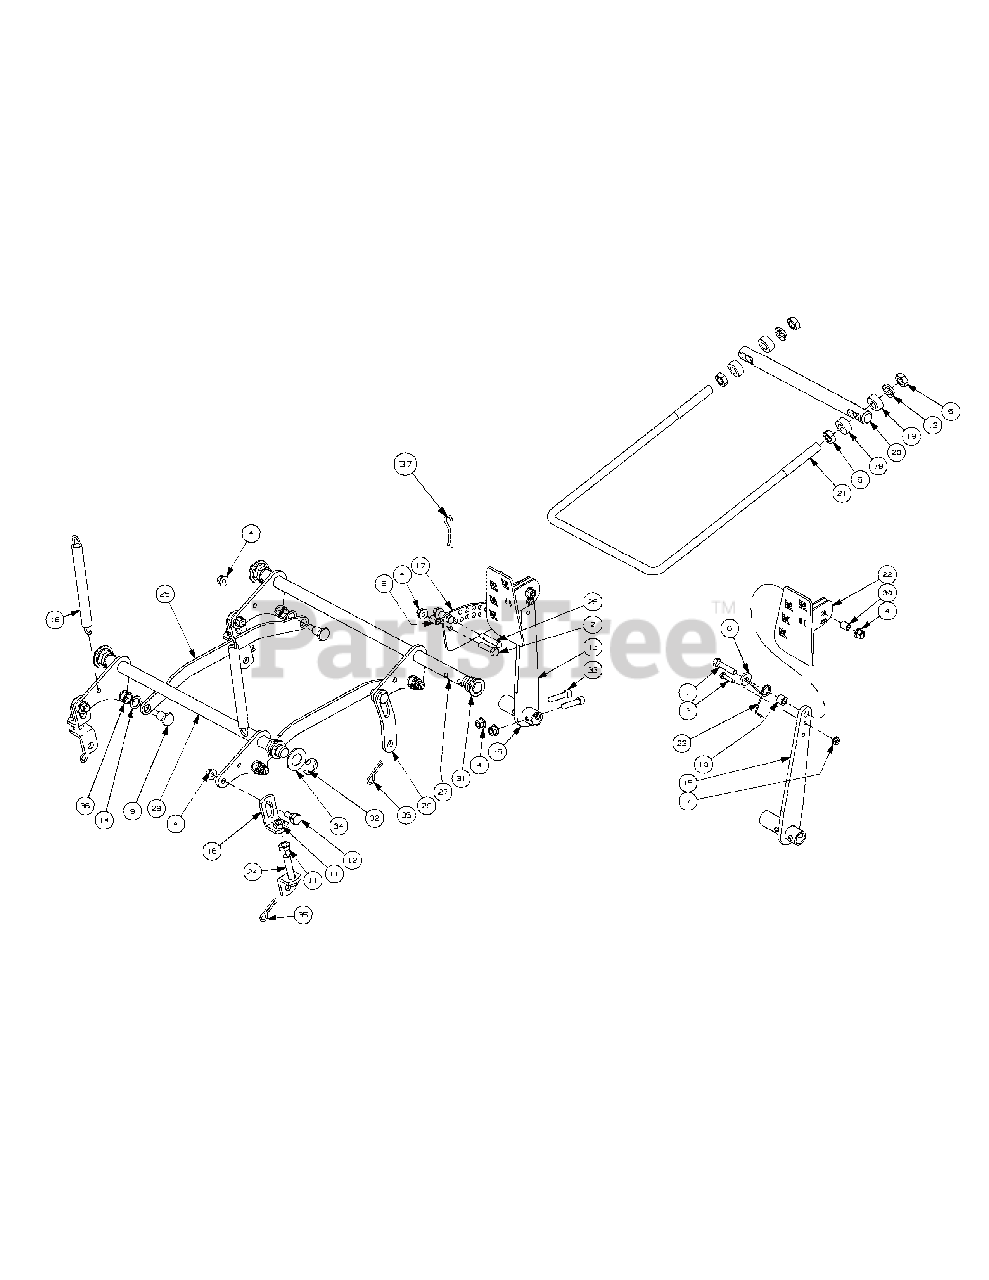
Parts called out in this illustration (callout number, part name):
1	Capscrew, 3/8-16 x 1-3/4
2	Hex Cap Screw, 3/8-16 x 1-1/2
3	Hex Cap Screw, 1/4-20 x 1.00
4	Nut, 3/8-16, Hex Flange Lock
5	Jam Nut, 5/8-11
6	Idler Washer
7	Nut, 1/4-20, Hex Flange Lock Nut
8	Spacer, .375 x .50 x .75 Lg
9	Shoulder Screw, 0.625 OD x .830 Lg.
10	Spacer, .625 OD x .385 ID x 1/2
11	Jam Nut, 1/2-20
12	Shoulder Screw, 3/8-16, .56 x .27
13	Lock Washer, 5/8
14	Washer, 1.00 OD x .625 ID x .048
16	Deck Lift Bracket
17	Index Plate
18	Extension Spring, 8.246 x .75 x .135
19	Spacer, .635 ID x 1.188 OD x .406
20	Trail Link Pivot Rod
21	Front Lift Rod
22	Foot Pedal Assembly
23	Foot Lift Torsion Spring
24	Lower Lift Bracket Assembly
25	Lift Link
26	Clevis Pin, .375 x 1.89 x 2.125
27	Front Shaft Assembly
28	Rear Shaft Assembly
29	Link Plate
30	Spacer, .380 ID x .500 OD x .605
31	Hex Flange Bearing, .875 ID
32	E Clip, .875 Dia.
33	Sockethead Capscrew, 3/8-16 x 1.50
34	Flat Washer, .94 x 1.75 x .11
35	Hair Pin
36	Spacer, .628 ID x .875 OD x .500
37	Hair Pin
